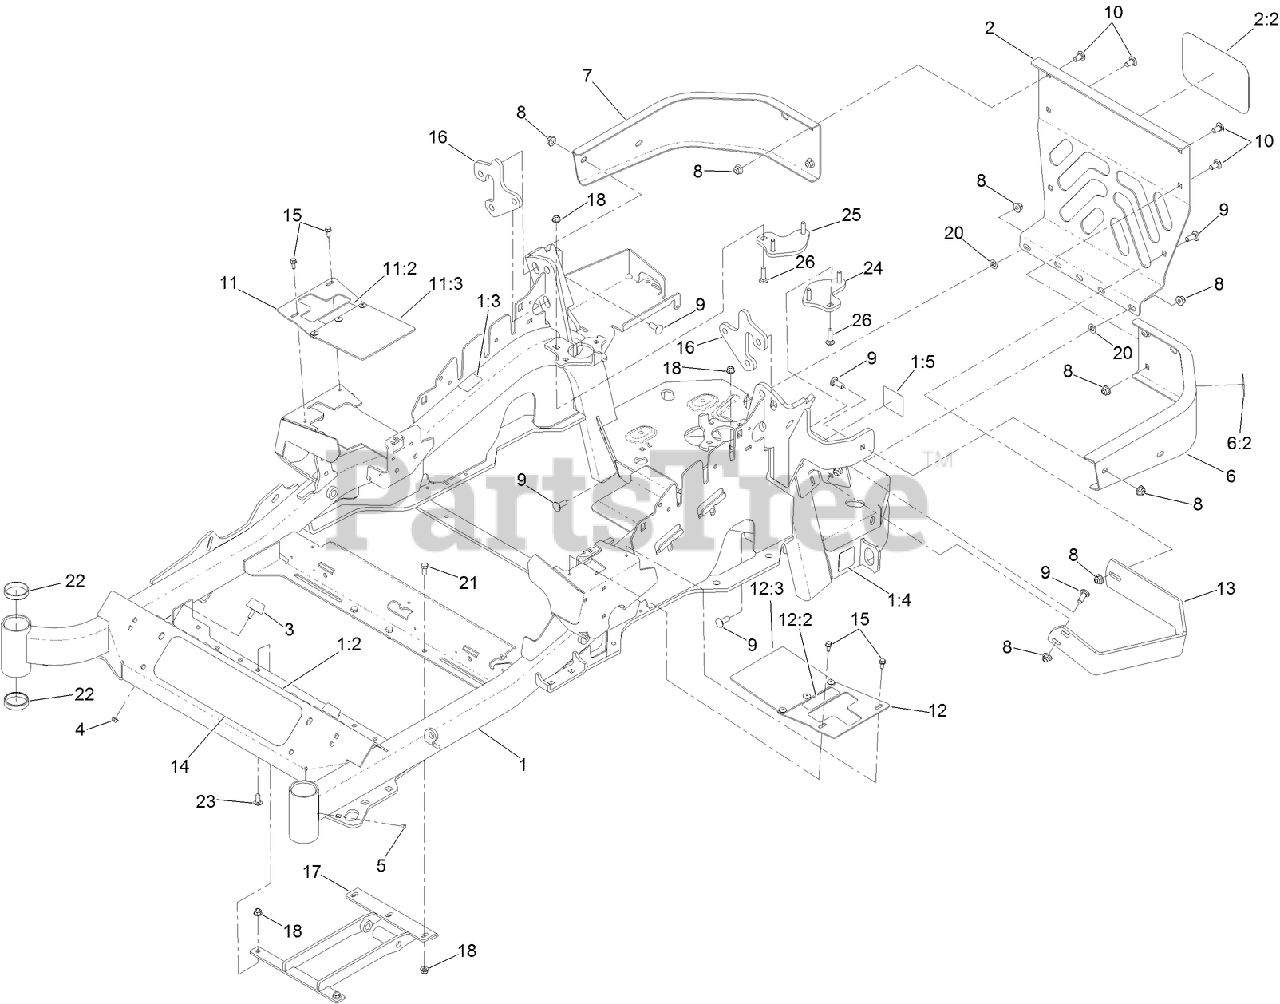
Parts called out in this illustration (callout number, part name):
1	MAINFRAME ASM
1:2	DECAL-DANGER
1:3	DECAL-WARNING
1:4	DECAL-HAZARD, PINCHED FINGER
1:5	DECAL-ARRESTOR, SPARK
2	REAR GUARD ASM
2:2	DECAL
3	BUMPER
4	NUT-HF
6	LH BUMPER ASM
6:2	DECAL-WARNING
7	BUMPER-RH
8	NUT-HF, NI
9	SCREW-CARR
10	SCREW-CARR
11	RH MOTION CONTROL COVER ASM
11:2	DECAL-CONTROL, MOTION
11:3	FLAP-RUBBER
12	LH MOTION CONTROL COVER ASM
12:2	DECAL-CONTROL, MOTION
12:3	FLAP-RUBBER
13	GUARD-MUFFLER
15	SCREW-HWH
16	PLATE-MOUNT, SHOCK
17	MOUNT-LOWER
18	NUT-HF, NI
20	NUT-PUSH
21	SCREW-HH
22	CUP-BEARING
23	SCREW-CARR
24	LH PLATE ASM (W/STUDS)
25	RH PLATE ASM (W/STUDS)
26	SCREW-CARR
